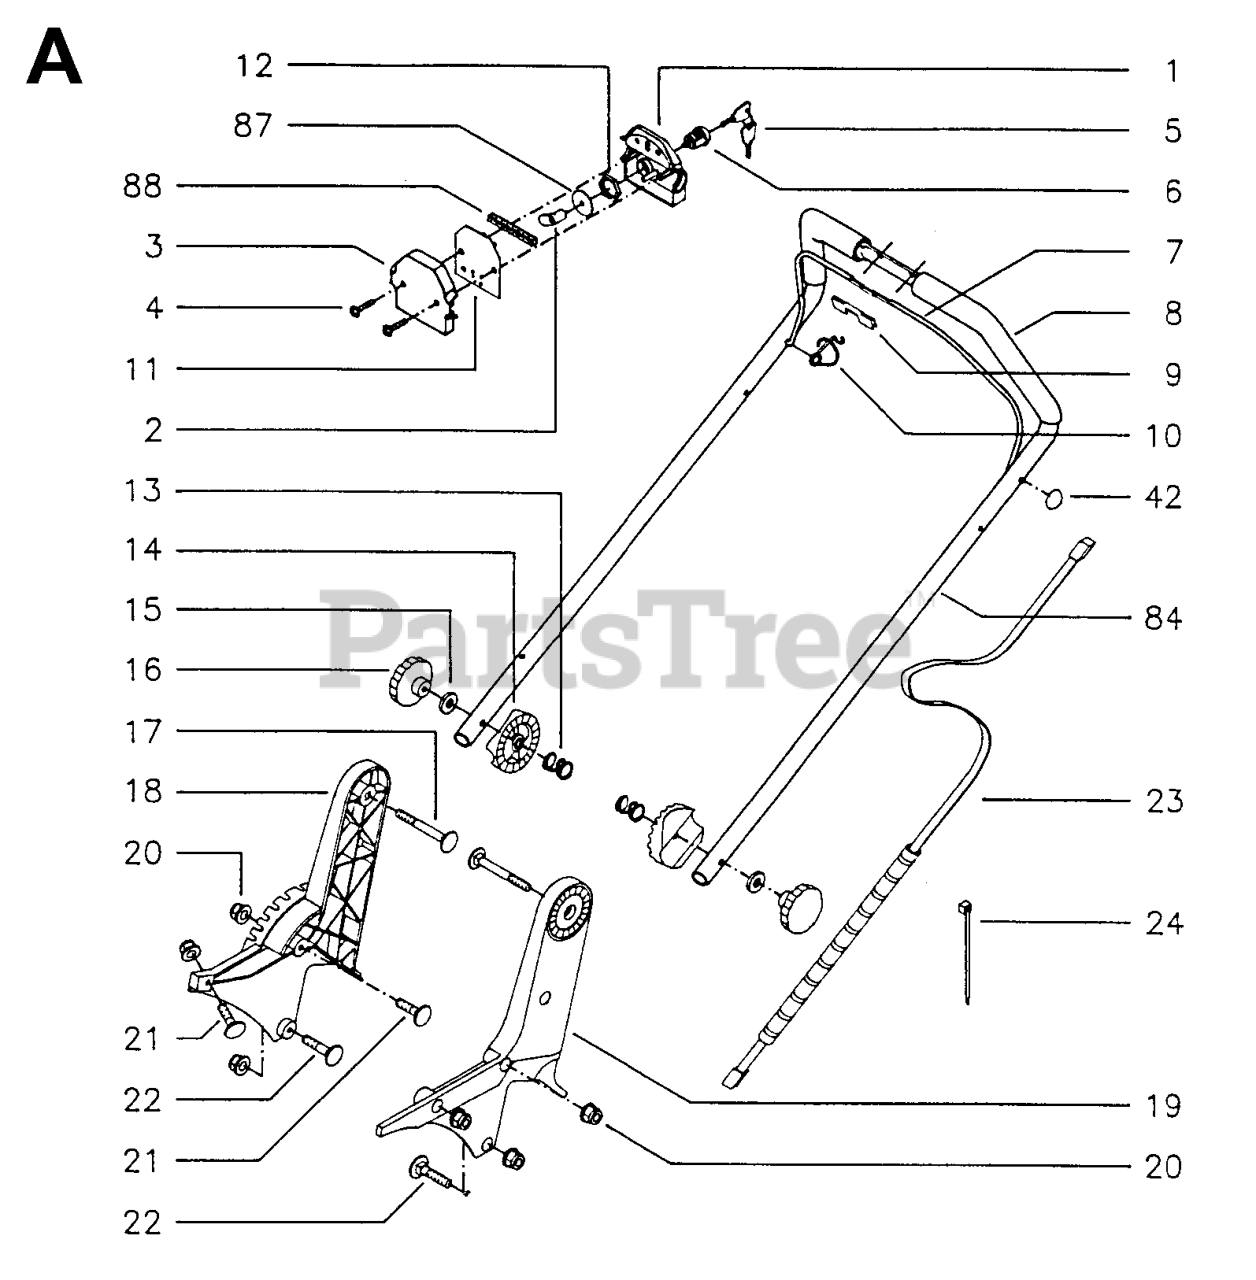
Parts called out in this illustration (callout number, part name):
8	VIBRATION DAMPENER
20	FLANGE NUT
21	REPL BY 515 71 16-20
